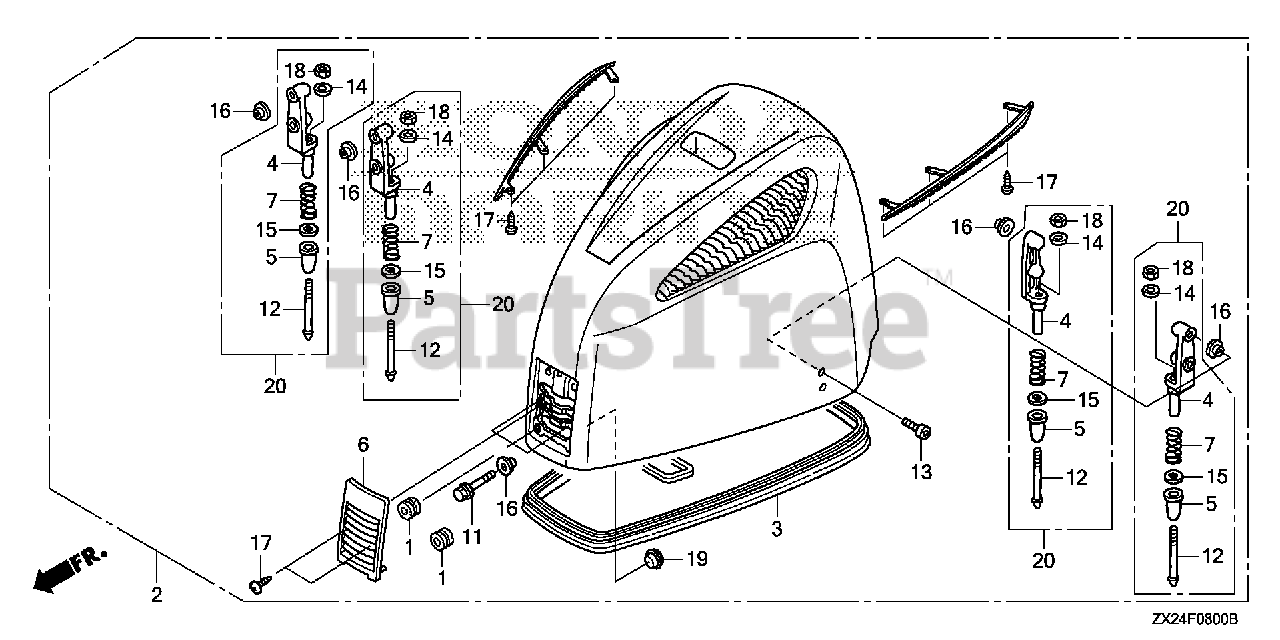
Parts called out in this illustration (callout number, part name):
1	GROMMET, AIR CLEANER HOUSING
2	COVER ASSY., ENGINE *NHB14M* (AQUA MARINE SILVER METALLIC)
2	COVER ASSY., ENGINE *NH565* (GRAND PRIX WHITE)
3	SEAL, ENGINE COVER
4	BRACKET, HOOK
5	DAMPER, HOOK
6	COVER, FR. *NHB14M* (AQUA MARINE SILVER METALLIC)
6	COVER, FR. *NH565* (GRAND PRIX WHITE)
7	SPRING, LOCK ADJUSTER
11	BOLT, FLANGE (6X20)
12	BOLT, COVER LOCK
13	BOLT, SOCKET (6X16)
14	WASHER, PLAIN (6MM)
15	WASHER, PLAIN (12MM)
16	COLLAR, DISTANCE (6.5X9X3)
17	SCREW, TAPPING (4X10)
18	NUT, HEX. (6MM)
19	PLUG, BLIND (20MM)
20	HOOK KIT, COVER
